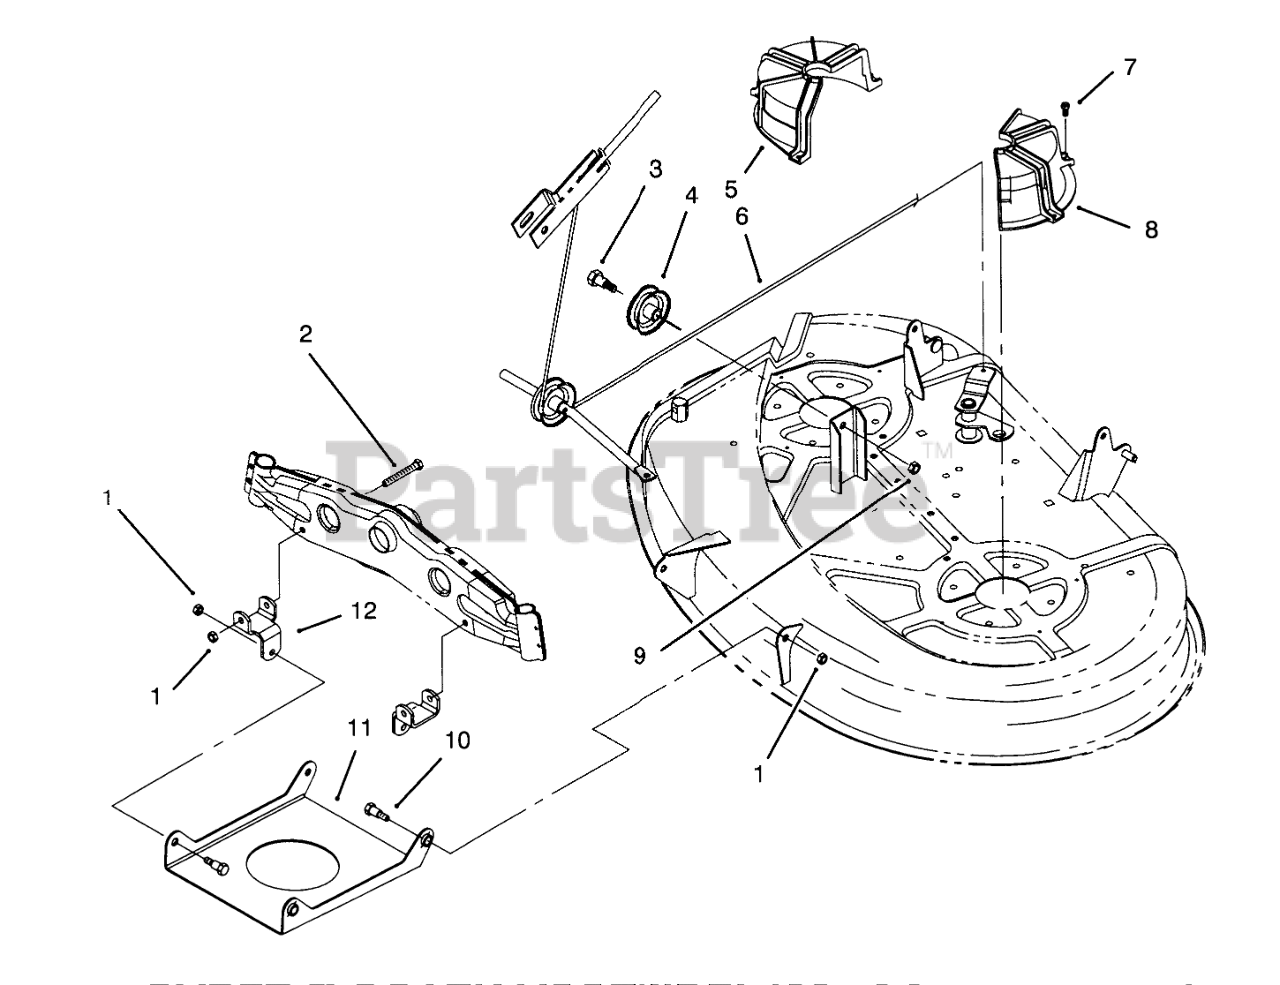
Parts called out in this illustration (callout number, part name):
1	NUT-LOCK, NI
2	SCREW-HH
3	SCREW-SHOULDER, HH
4	PULLEY, CABLE
5	GUIDE-BELT, RH
6	DECK ENGAGE CABLE
7	SCREW-HWHTF
8	GUIDE-BELT, LH
9	NUT-LOCK, NI
10	BOLT-SHOULDER
11	Pan-Front Deck Suspension
12	Bracket-Deck Suspension
